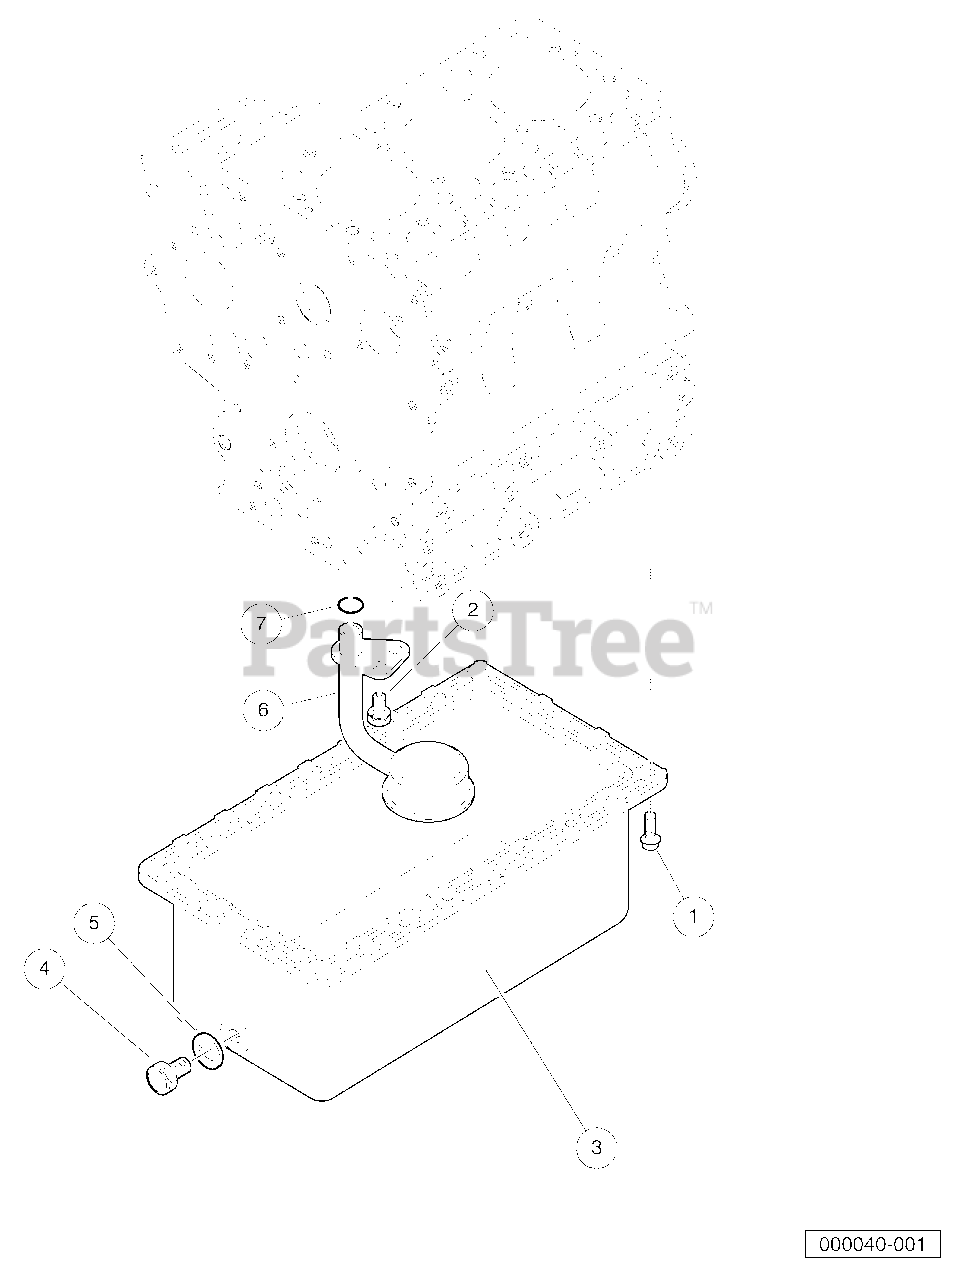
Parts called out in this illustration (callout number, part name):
1	Bolt, M6 X 1 X 14
2	Bolt, M8 X 1.25 X 15
4	Plug, Drain, M12 X 14
5	Gasket, 20 X 13
6	Filter, Oil, Pick Up
7	O Ring, 20 X 17
